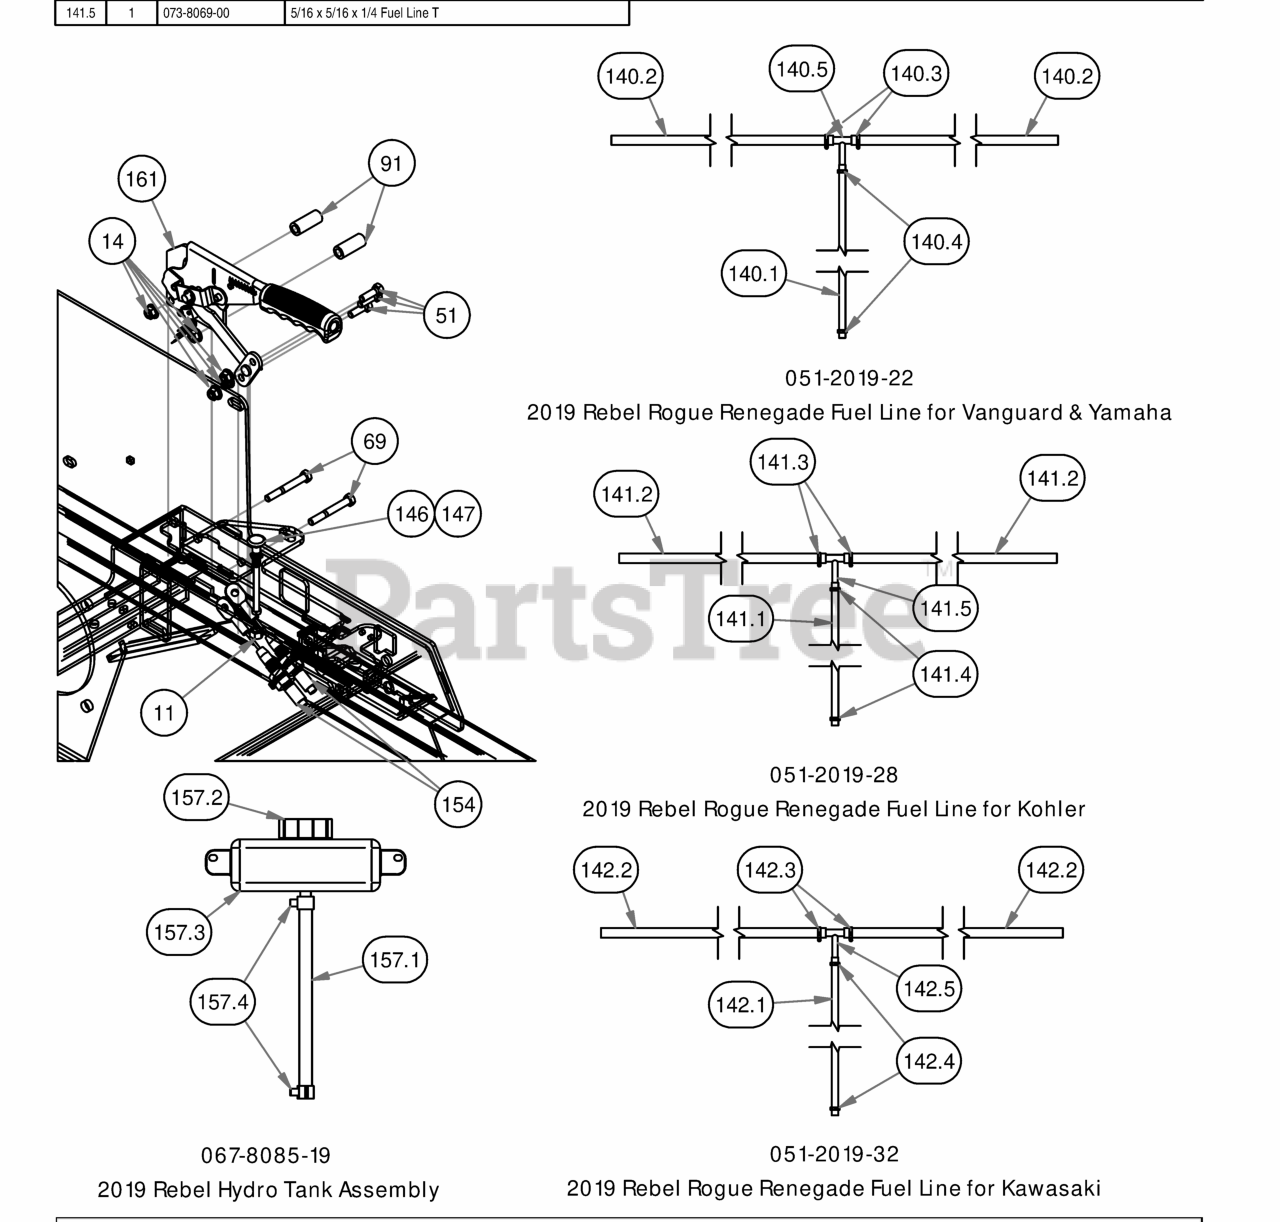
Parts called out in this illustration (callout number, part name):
11	3/8" Fine Threaded Jam Nut
14	5/16" Nylon Flange Nut
51	5/16" x 1" Bolt
69	5/16" x 2 1/2" Bolt
91	2019 Outlaw Brake Handle Spacer .625 x 1.5
140.1	1/4" Fuel Line Hose
140.2	5/16" fuel line hose
140.3	5/16 Fuel Line Clamp
140.4	1/4 Fuel Hose Clamp
140.5	5/16 x 5/16 x 1/4 Fuel Line T
141.1	1/4" Fuel Line Hose
141.2	5/16" fuel line hose
141.3	5/16 Fuel Line Clamp
141.4	1/4 Fuel Hose Clamp
141.5	5/16 x 5/16 x 1/4 Fuel Line T
142.1	1/4" Fuel Line Hose
142.2	5/16" fuel line hose
142.3	5/16 Fuel Line Clamp
142.4	1/4 Fuel Hose Clamp
142.5	5/16 x 5/16 x 1/4 Fuel Line T
147	Choke for 36Hp Vanguard & FX1000 Kawasaki
154	Long Brake Cable
157.1	5/8 Braided Hose
157.2	Hydraulic Tank Cap
157.3	Expansion Tank Outlaw
157.4	5/8 Wire Clamp-Outlaw Only
161	2019 Brake Handle Assembly
